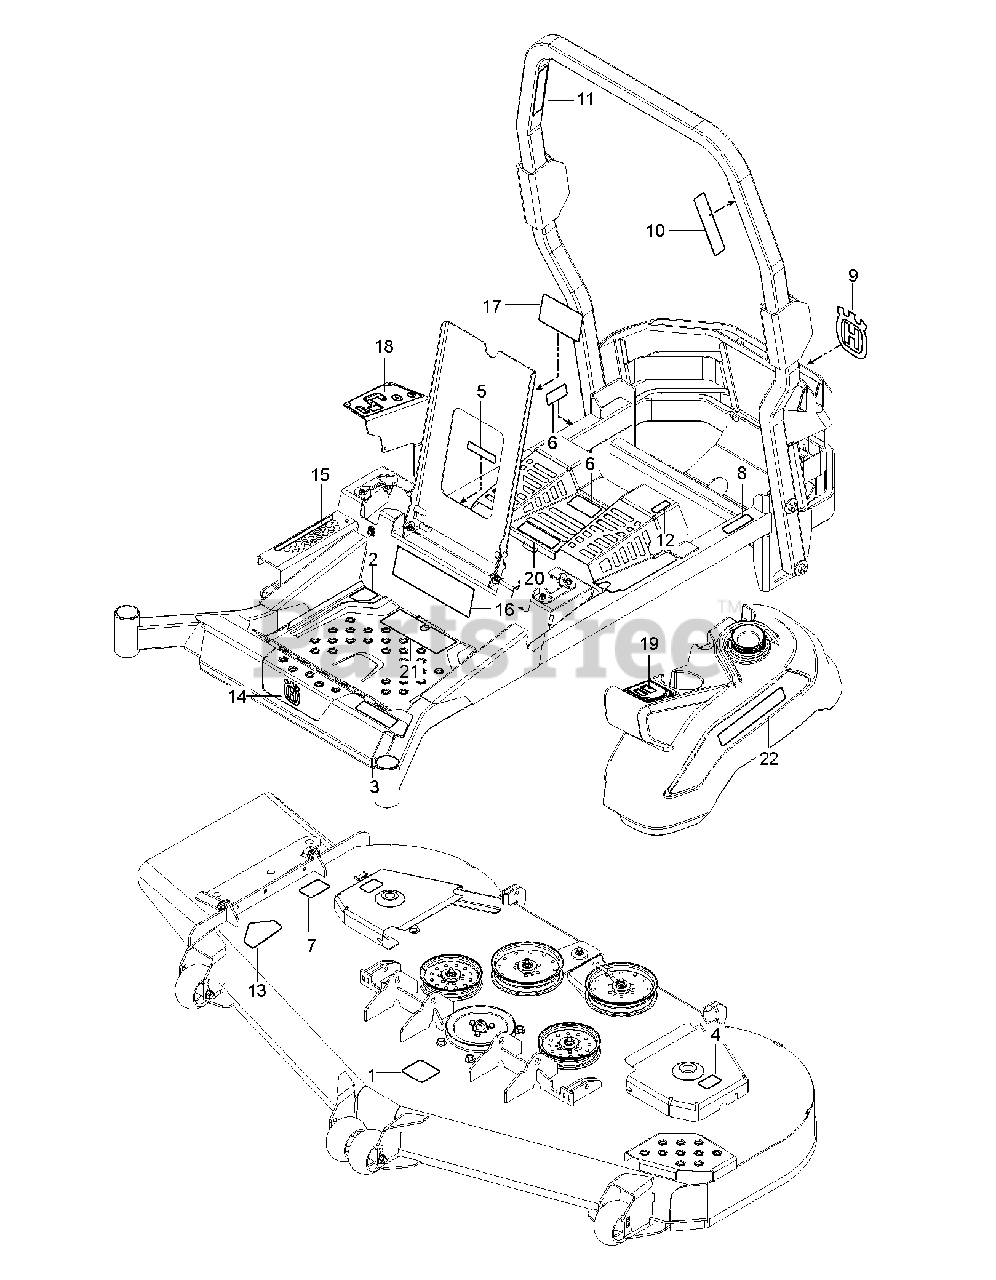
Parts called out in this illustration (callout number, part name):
1	DECAL, BELT ROUTING
1	DECAL, 72" BELT ROUTING
2	Decal, ZTR Saddle Warning PZ500 Engine
3	Decal, ZTR PZ500SERIES Z554X
4	DECAL.DECK.6MIL.EURO.NOSTEP
5	EURO DECAL-BATTERY WARNIN6
6	DECAL, BELT DRIVE
7	DECAL.DECK.6MIL./DEF.SHLD.WARN
8	DECAL, WARNING SPARK ARRESTOR
9	DECAL, CROWN H, 110MM
10	DECAL ROPS DECAL DECAL.ROPS.PZ
11	DECAL, ROPS, WARNING
12	DECAL, FUSE
13	DECAL, DECK DEFLECTOR, WARNING
14	DECAL.BADGE.55MM.CROWNH.HUSQ
15	Decal, PZ500 Deck Lift Husqvarna
16	Decal, ZTR Saddle COMM PZ500
17	Decal, PZ500 Maintenance/SVC 2018
18	DECALZTR.CONTROLPANEL.PZ500.RH
19	Decal, ZTR Control Panel PZ500 LH
20	Decal, ZTR TRANCOVER Warning PZ500
21	Warning Decal
22	DECAL.HUSQVARNA.210MM
